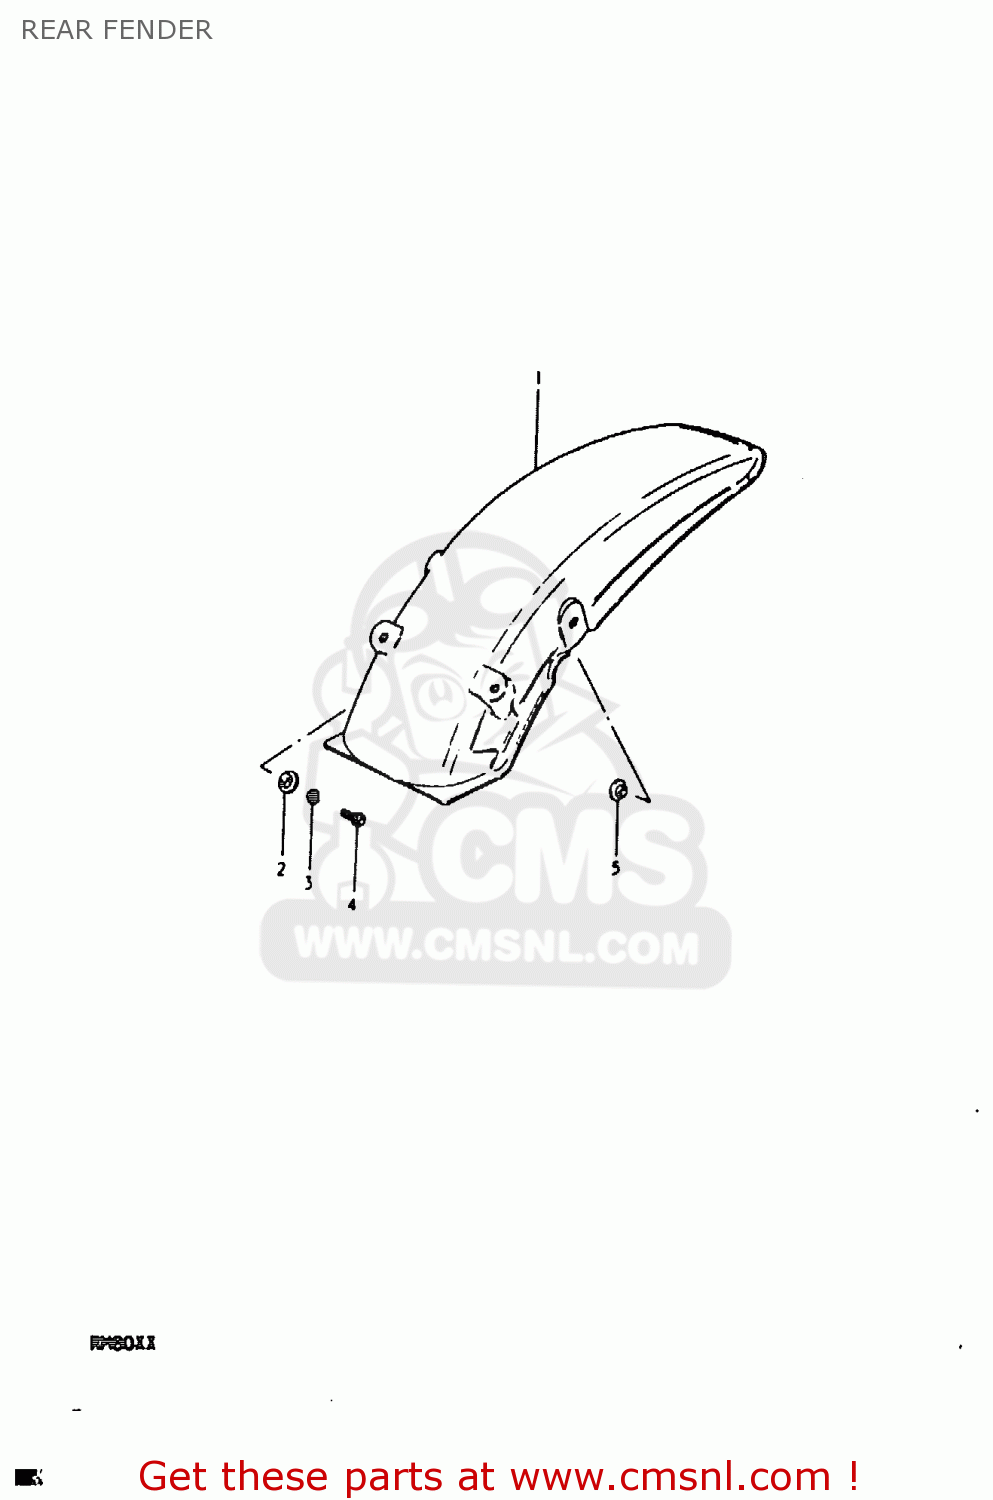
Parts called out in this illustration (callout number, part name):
1	FENDER,RR
2	WASHER
3	LOCK WASHER
4	BOLT, UPPER
5	WASHER
